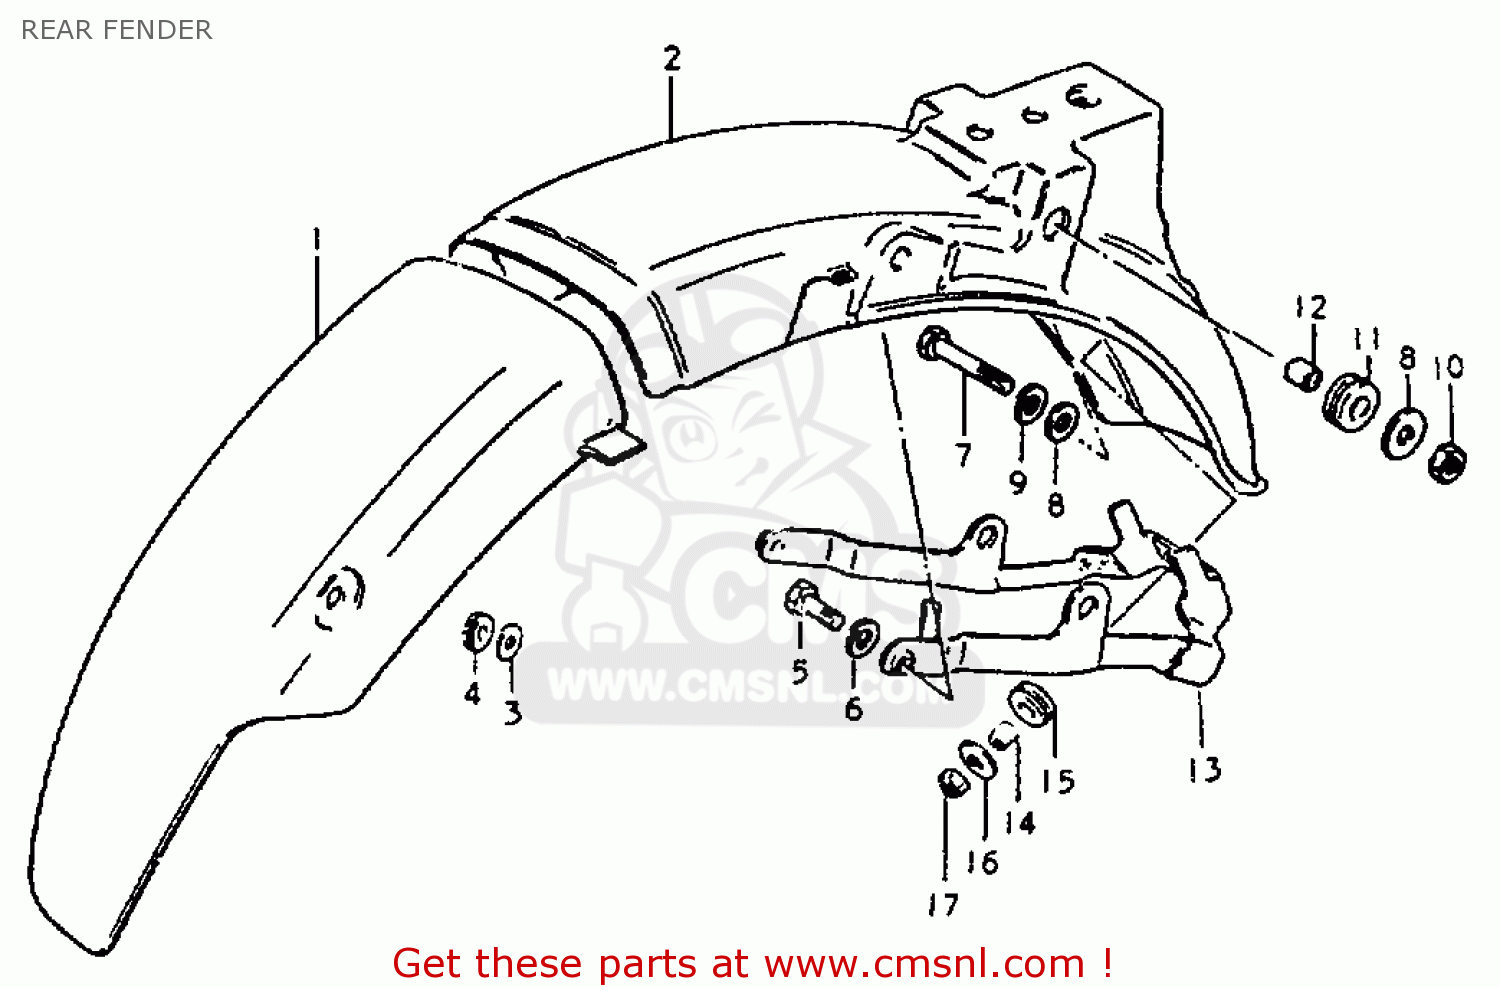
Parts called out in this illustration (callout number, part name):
1	BODY, REAR FENDER FRONT
2	FENDER, REAR
3	WASHER
4	CUSHION
5	BOLT, UPPER
6	LOCK WASHER
7	BOLT
8	WASHER
9	LOCK WASHER
10	NUT
11	CUSHION
12	SPACER (8.2X12X7.5)
13	REINFORCEMENT
14	SPACER (6.1X9X9)
15	CUSHION
16	WASHER(6,5X22X1.6)
17	NUT
